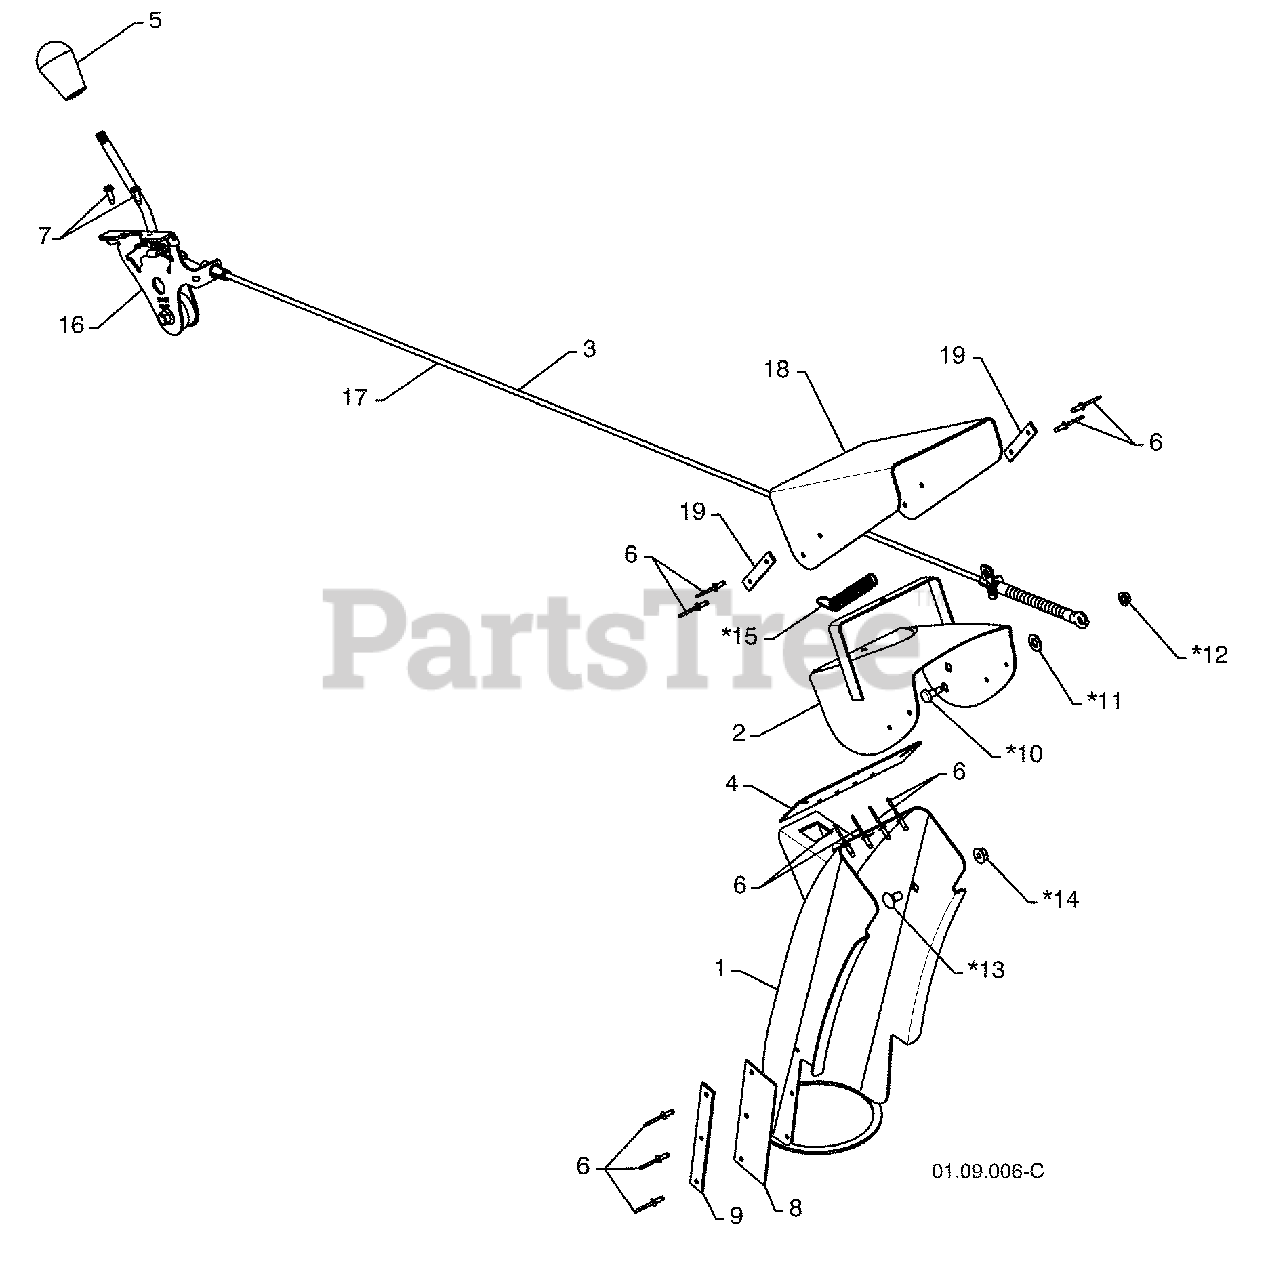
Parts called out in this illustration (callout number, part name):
1	CHUTE WELDMENT
2	DEFLECTOR WELDMENT
3	DEFLECTOR CONTROL ASSEMBLY
4	DEFLECTOR SEAL
5	KNOB BLACK
7	SCREW 10-24 X .625
8	CHUTE SNOW SHIELD
9	SHIELD RETAINER STRAP
10	SHOULDER BOLT 1/4-20 X .375
11	PLASTIC WASHER
12	NUT 1/4-20
13	CARRIAGE BOLT 3/8-16 X .625
14	NUT 5/16-18
15	DEFLECTOR SPRING
16	(SERVICE PART) DEFLECTOR CONTROL
17	(SERVICE PART) DEFLECTOR CABLE GRAY
18	DEFLECTOR SHIELD
19	DEFLECTOR SHIELD STRAP
